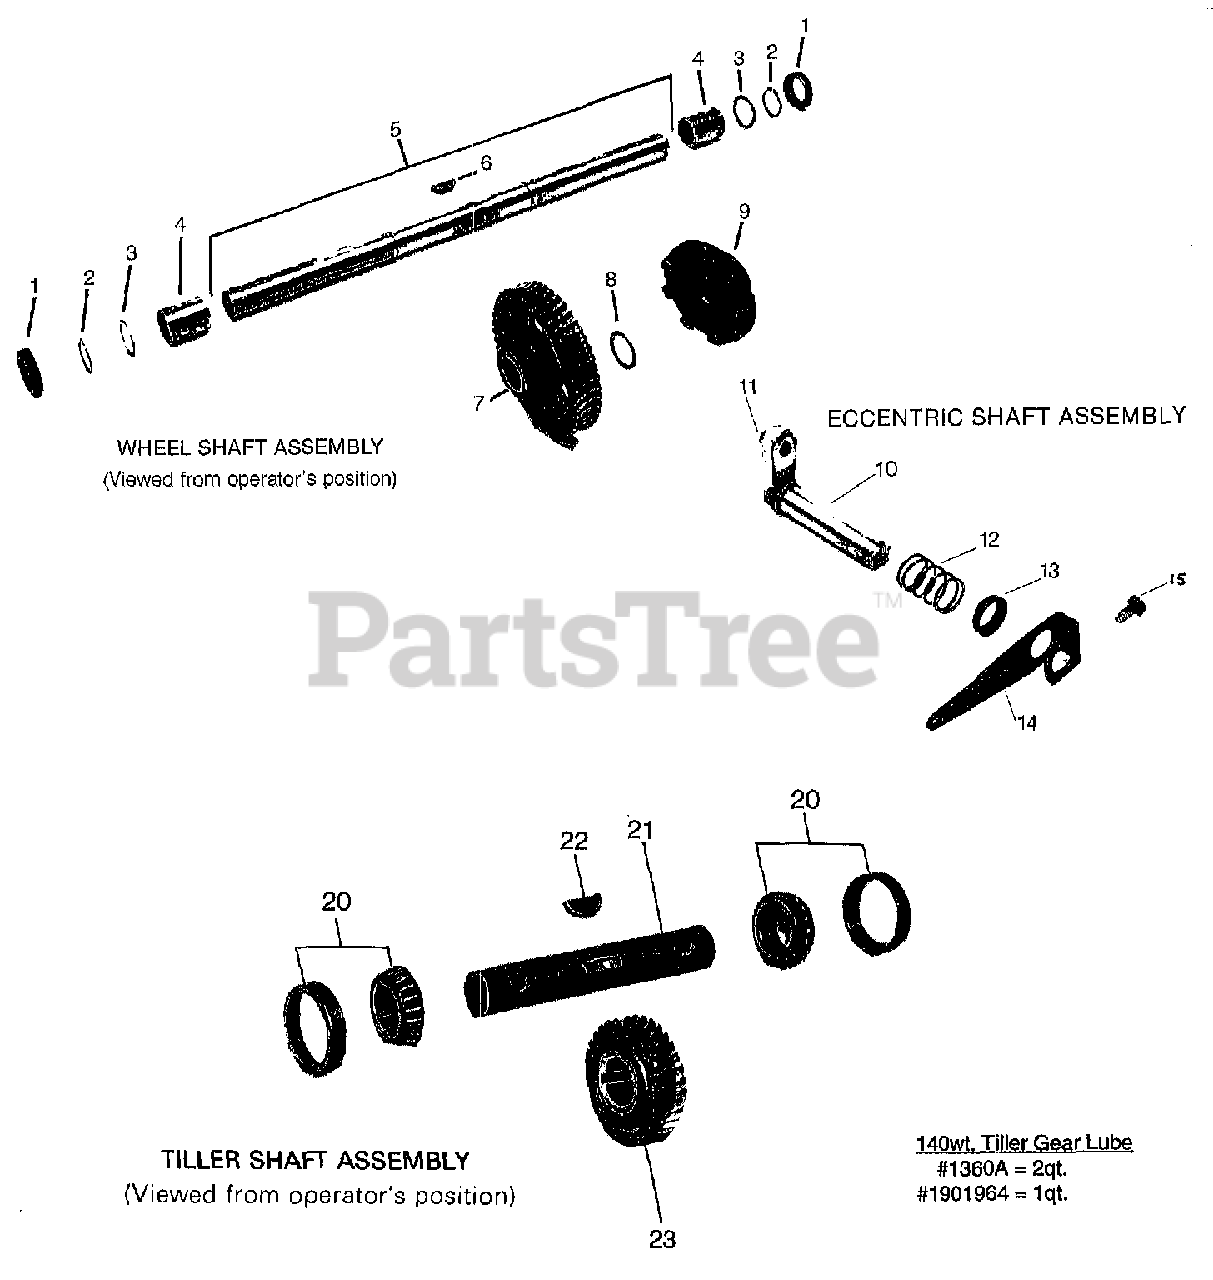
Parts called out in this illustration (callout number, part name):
1	OIL SEAL-left and right sides
2	RING-retaining, heavy-duty, external
3	SHIM - 1 1/64" I.D., .062" thick
4	BUSHING -
5	WHEEL SHAFT -
6	KEY - Hi-Pro (1/4" x 1 5/16"), clutch to wheel shaft
7	GEAR - wheel drive (worm gear), cast iron
8	SHIM - between key and gear (1.016" I.D. x 1.468" O.D. x .062" thick)
9	CLUTCH - wheel drive, cast iron
10	ECCENTRIC SHAFT - wheel clutch shifting
11	PIN - eccentric shaft
12	SPRING -
13	OIL SEAL - eccentric shaft
14	LEVER - eccentric shaft
15	BOLT - hex head, 1/4"-20 x 1/2"
20	BEARING - tapered roller (with race), for tiller shaft
21	TILLER SHAFT -
22	KEY - woodruff, 1/4" x 1 1/4", for tiller shaft/worm gear
23	WORM GEAR - bronze, tiller drive
